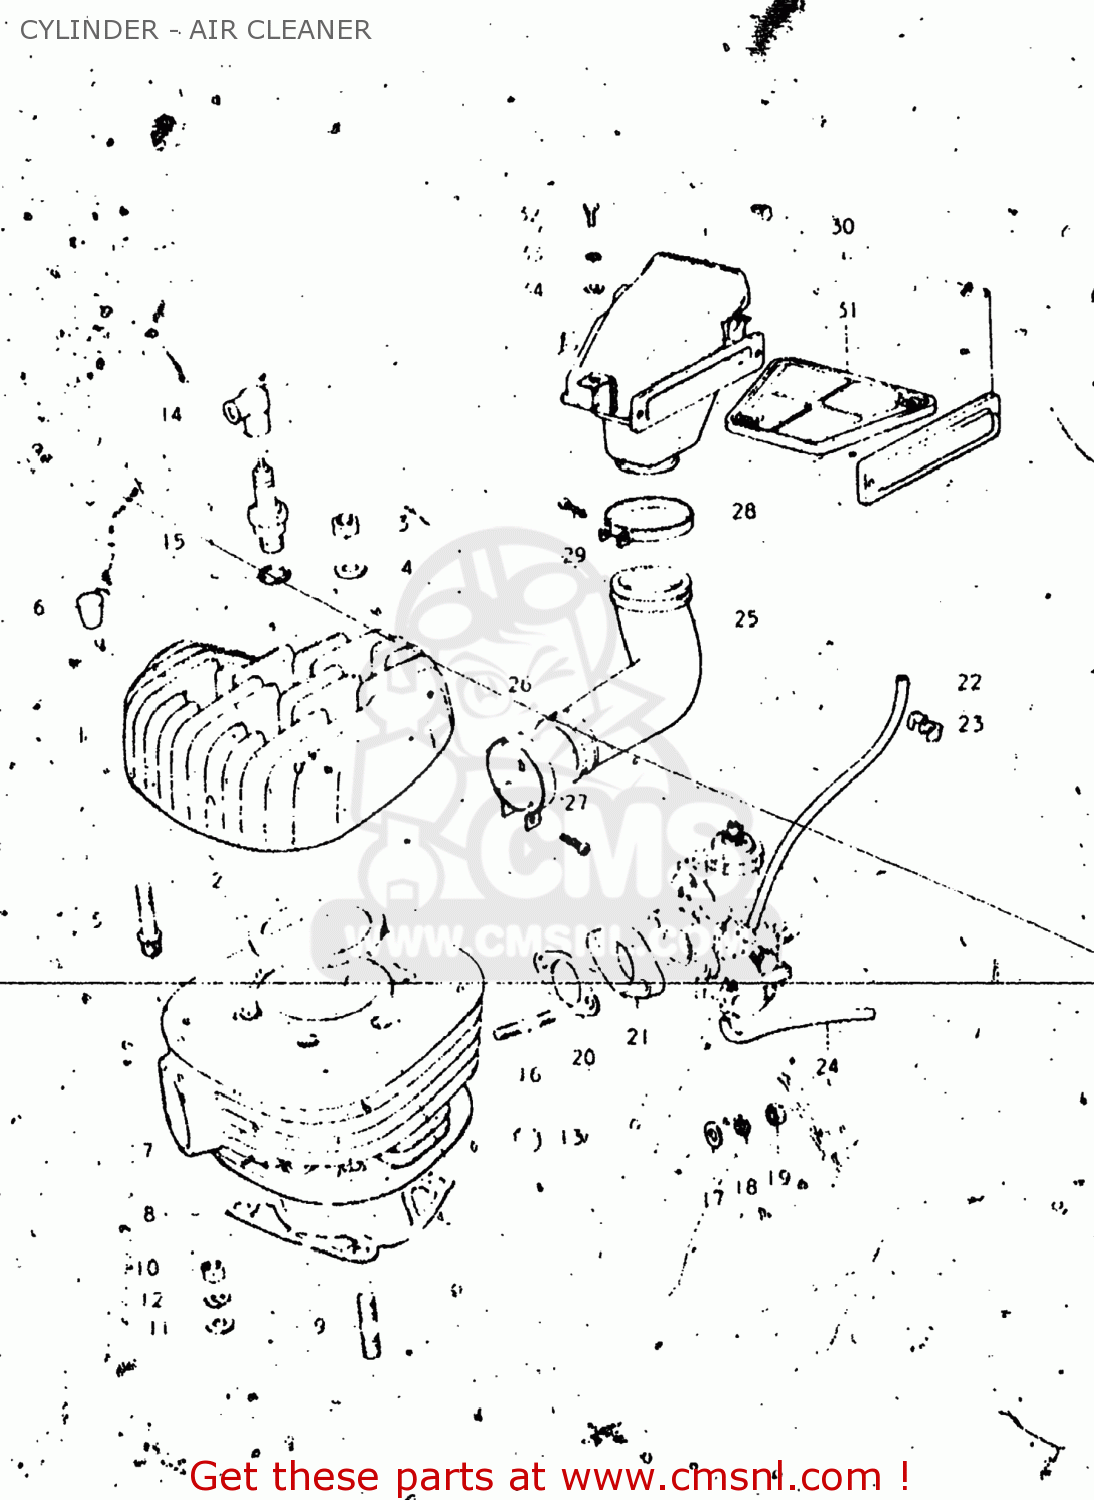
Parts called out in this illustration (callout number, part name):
0	GASKET SET (MCA)
1	HEAD,CYLINDER
2	GASKET,CYLINDER HEAD (NAS)
3	NUT (8MM)
4	WASHER
5	BOLT,STUD
6	PAD,CYLINDER HEAD
7	CYLINDER
8	GASKET,CYLINDER (MCA)
9	STUD 10X30
10	NUT
11	WASHER
12	LOCK WASHER
13	PAD,CYLINDER
14	CAP ASSEMBLY,SPARK PLUG
15	SPARK PLUG
16	STUD BOLT
17	WASHER
18	LOCK WASHER
19	NUT
20	GASKET,CARBURETOR (NAS)
21	INSULATOR,CARBURETOR
22	HOSE
23	CLIP
24	HOSE
25	TUBE,AIR CLEANER OUTLET
26	CLAMP
27	SCREW
28	CLAMP
29	SCREW TAPP.
30	CLEANER ASSEMBLY,AIR
31	FILTER,AIR CLEANER
32	BOLT
33	LOCK WASHER
34	WASHER
